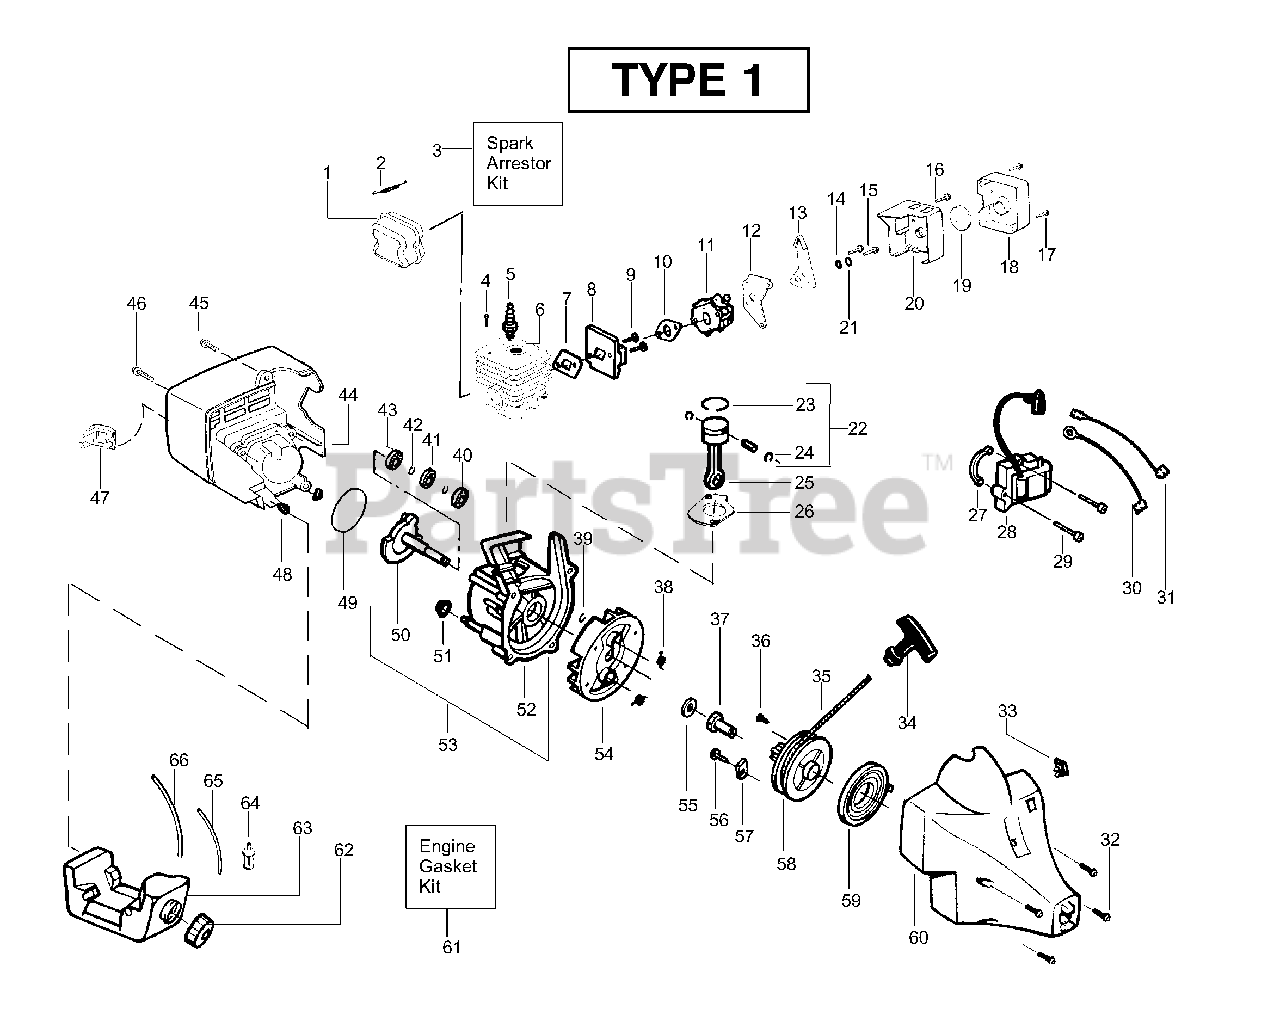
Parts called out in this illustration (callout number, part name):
1	Kit - Muffler
2	Muffler Spring
3	Kit-Spark Arrestor
4	Screw-Cylinder
5	Spark Plug (RCJ 8Y)
6	Kit - Cylinder
7	Gasket-Cyl/Carb.(kit)
8	Kit - Carb. Adaptor
10	Gasket-Carb. (kit)
11	Kit - Carburetor Ass'y
12	Choke Plate Mounting
13	Choke Lever
18	Cover-Air Box
19	Foam-Air Filter
21	Spacer-Choke
22	Kit - Piston
23	Piston Ring
24	Retainer-Piston Pin
25	Assy-Connecting Rod
26	Gasket-Cylinder (kit)
27	Spacer-Module
28	Ignition Module
30	Assy-Ground Wire
31	Assy-Leadwire
32	Screw
33	Kit-Momentary Switch
34	Handle-Starter
35	Kit - Rope
37	Coupling-Drive
38	Spring-Starter Dog
39	Retain. Ring-C'shaft
40	Bearing-Outer
41	Seal-C'case
42	Retainer Ring-C'case
43	Bearing-Inner
46	Screw
47	Guard-Muffler
48	Isolator-Shroud
49	O-Ring-C'case(kit)
50	Assy-Crankshaft
51	Isolator-Crankcase
52	Assy-Crankcase
53	Assy-C'case & C'shaft
54	Assy-Flywheel
55	Washer-Flat
57	Retainer-Can
58	Kit-Starter Pulley
59	Spring-Starter
60	Assy-Fan Housing
61	Kit-Engine Gasket
62	Assy-Fuel Cap
63	Assy-Fuel Tank
64	Assy-Fuel Pickup
65	Kit-Fuel Line
66	Kit-Fuel Line
